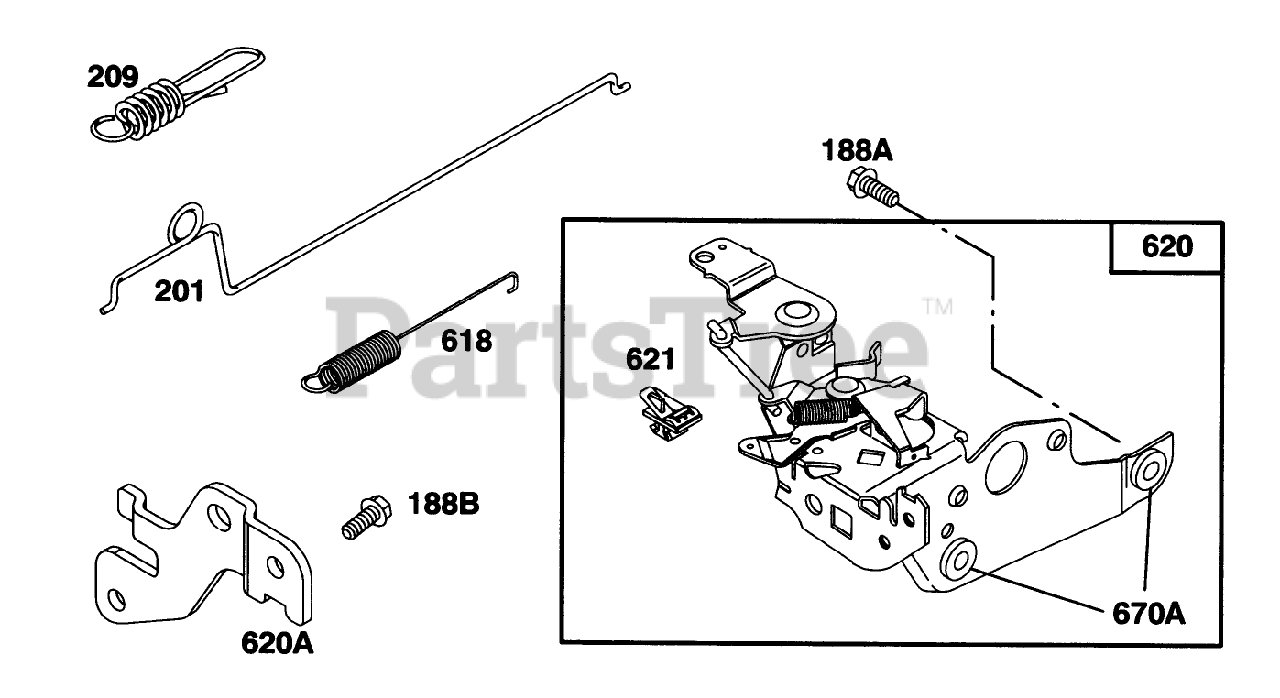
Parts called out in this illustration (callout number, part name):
188A	Screw-Hex.
188B	Screw-Hex.
201	Link-Govemor
209	Spring-Govemor
618	Spring-Choke
620	Bracket-Carburetor
621	Switch
670A	Spacer
